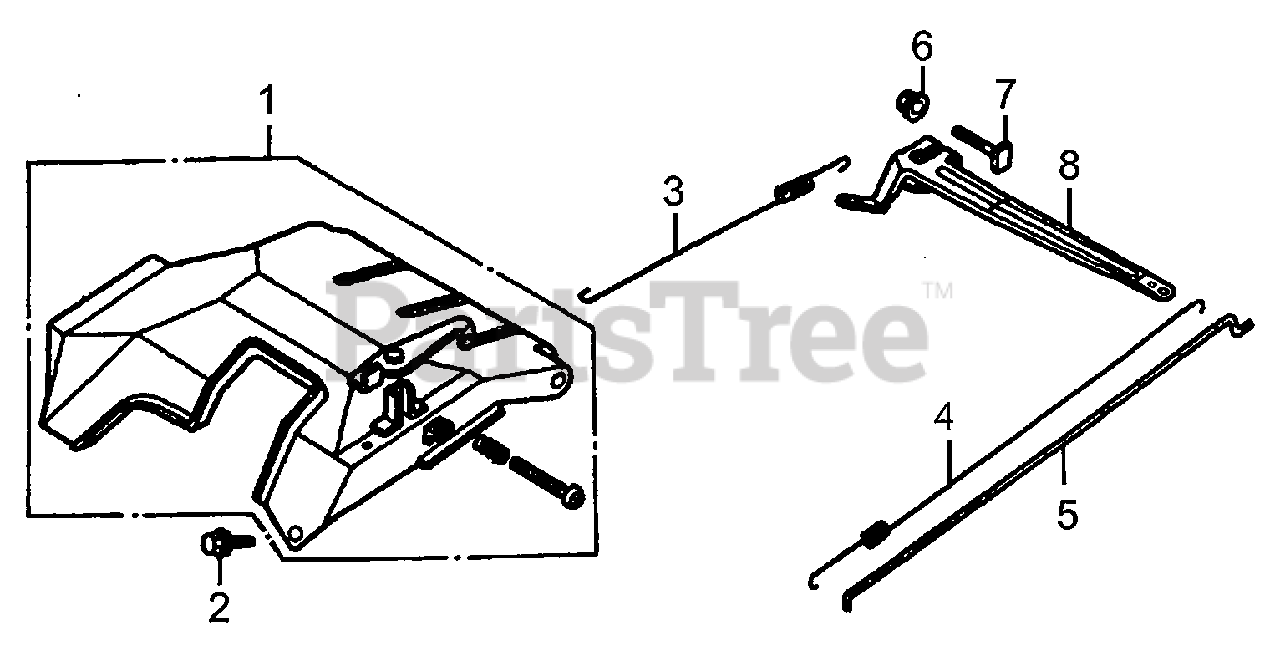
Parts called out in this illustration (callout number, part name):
1	CONTROL ASSY.
2	BOLT' FLANGE' 6×12
3	SPRING' GOVERNOR A
4	SPRING' GOVERNOR B
5	ROD' GOVERNOR
6	NUT' FLANGE' M6
7	BOLT' GOVERNOR ARM
8	ARM' GOVERNOR
